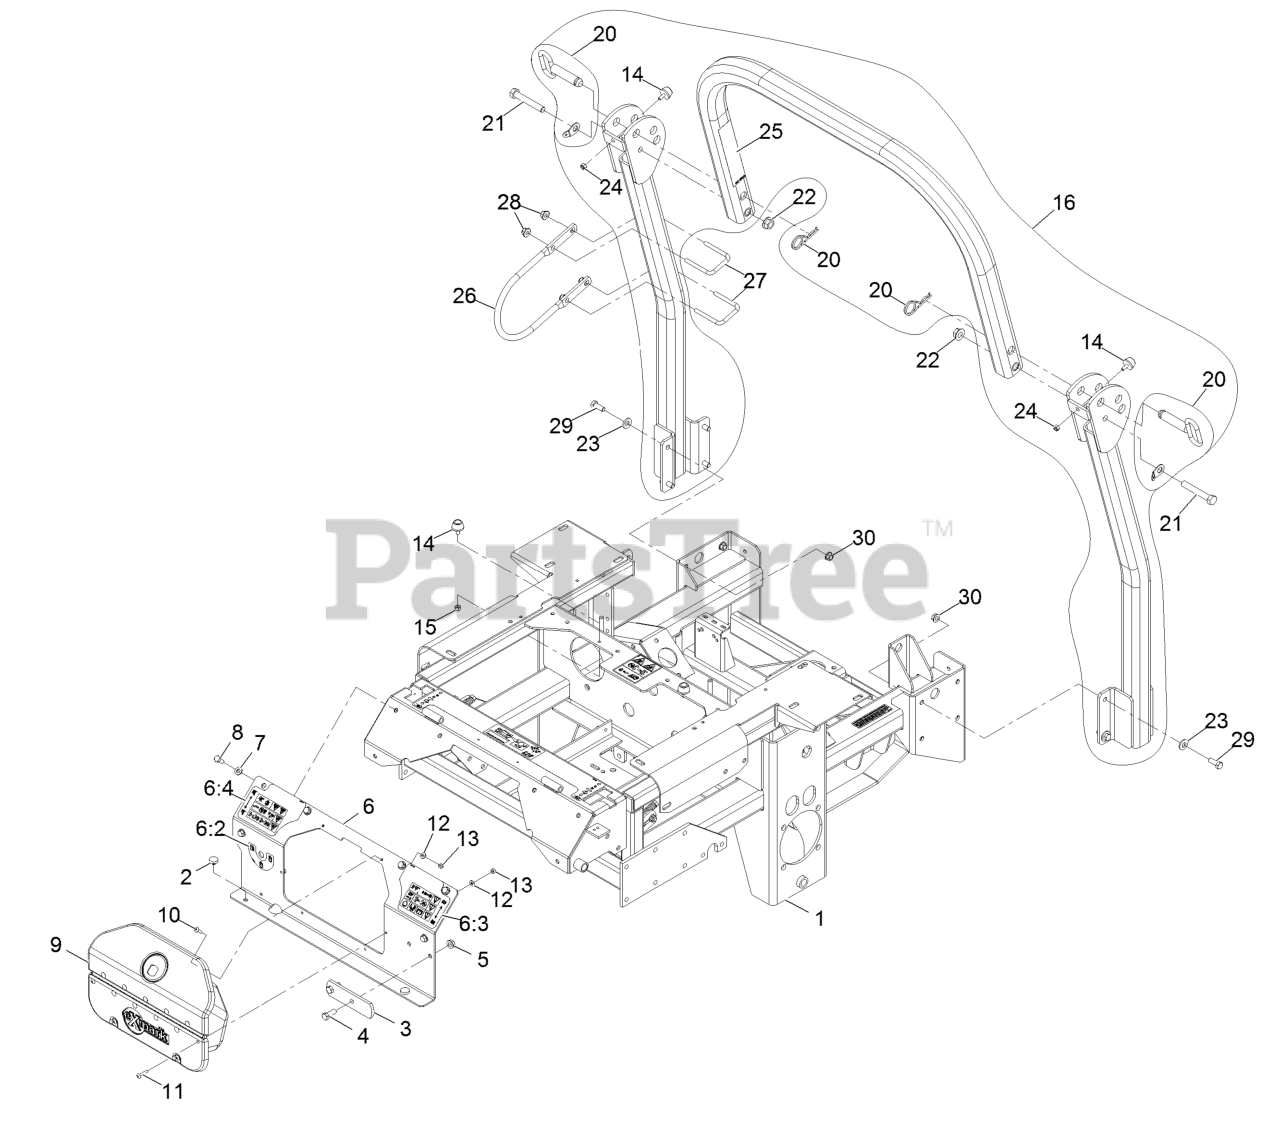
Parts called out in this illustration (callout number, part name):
1	ASM,KDXS ENGINE DECK W/DE
3	STOP-BRAKE, PARK
4	SCREW-HH
5	NUT-HHF, WHIZ
6	ASM, CONSOLE W/DECALS
6:2	Decal-Fuel
6:3	Decal-Console LH
6:4	Decal-Console RH
7	WASHER-PLAIN
8	SCREW-HH
9	ASM,CUBBY
10	SCREW-HEAD, TRUSS
12	WASHER-FLAT
13	NUT-LOCK, NI
14	BUMPER-RUBBER
15	NUT-LOCK, NI
16	KIT, 06 XS ROPS
20	PIN-FOLD, ROPS
21	SCREW-HH
23	WASHER-BELLEVILLE
24	NUT-LOCK, NI
25	DECAL-WARNING
28	NUT-HF, NI
29	SCREW-HH
30	NUT-HHF, WHIZ
